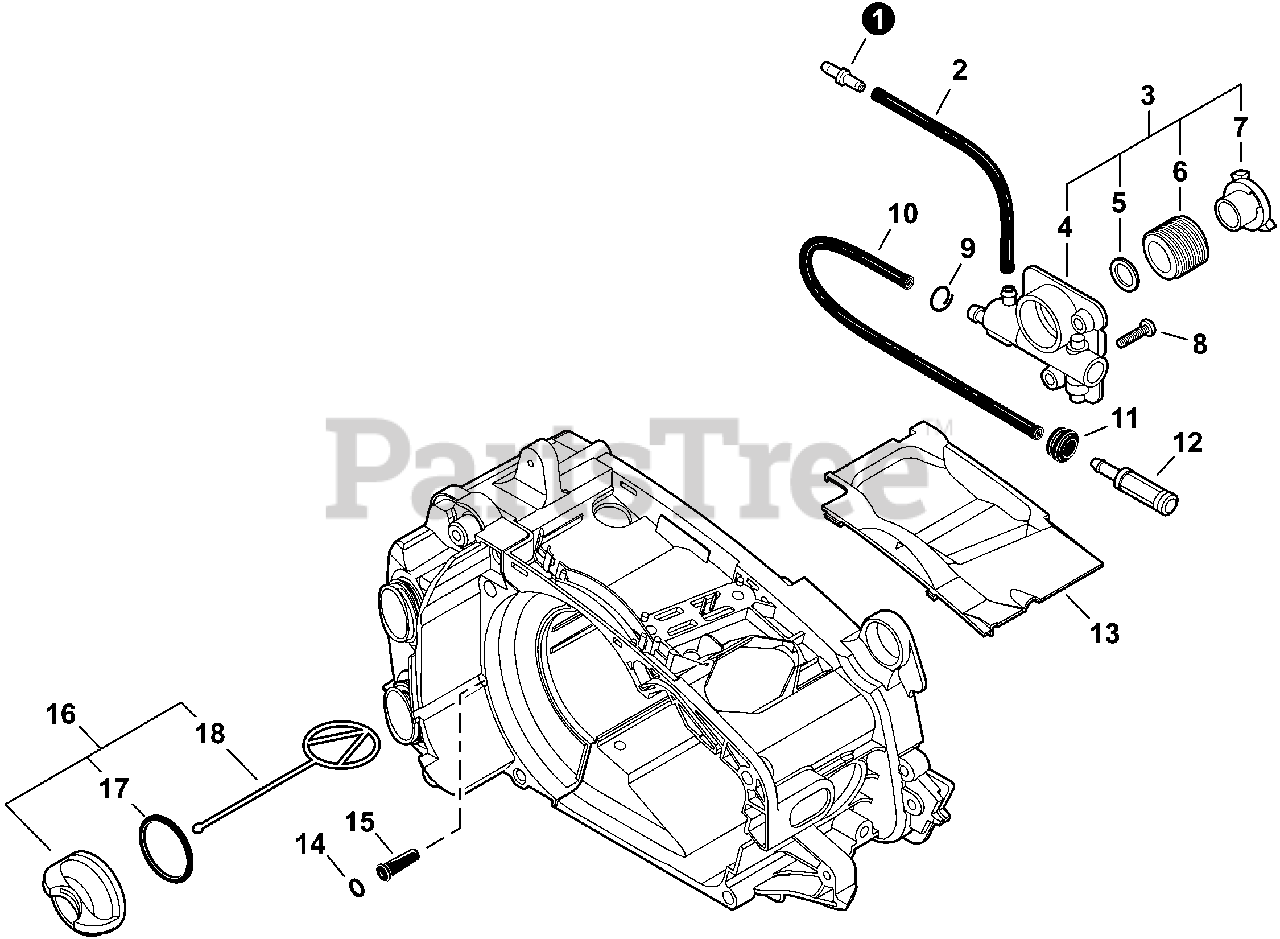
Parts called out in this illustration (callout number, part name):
1	CONNECTOR, PIPE
2	PIPE, 3×6×45 BLACK
3	AUTO-OILER ASSY
4	AUTO-OILER ASSY
5	WASHER 10.5×17.4×1.8
6	GEAR, WORM
7	COLLAR 10
8	BOLT, TORX 4×12
9	CLIP Ø6.5 MM
10	PIPE 3×6×160
11	GROMMET
12	FILTER, OIL
13	COVER, DUST
14	O-RING S-4
15	VENT ASSY
16	CAP ASSY - BLACK
17	O-RING 18
18	CONNECTOR, CAP L= 60 MM
